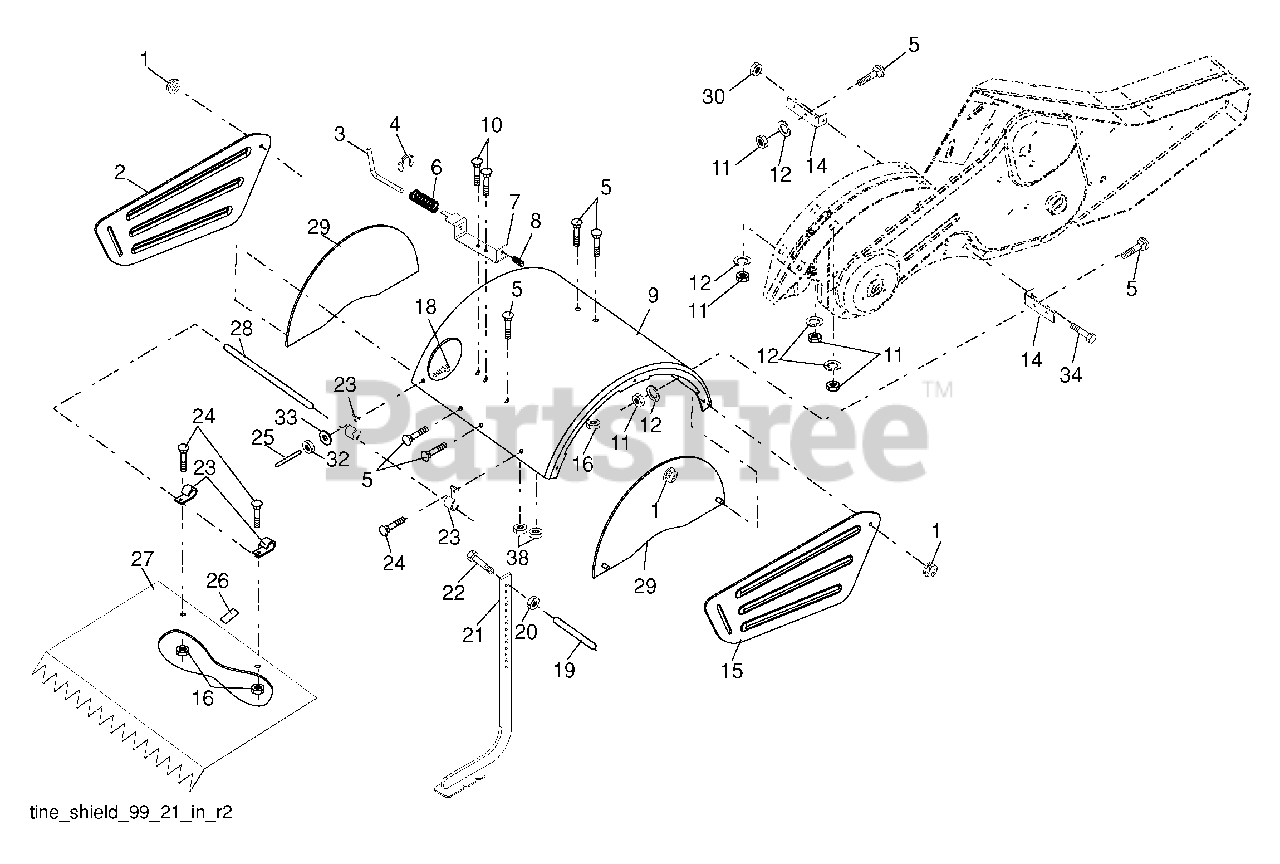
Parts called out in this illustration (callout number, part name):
1	Nut, Lock Hex Flange 5/16-18
2	Shield, Side, Outer L. H.
3	Pin, Stake, Depth
4	Ring, Klip
5	Bolt 5/16-18 x 3/4
7	Bracket, Latch
8	Spring, Depth Stake
9	Shield, Tine
10	Bolt Rdhd Sqnk 5/16-18 x 1
11	Nut, Hex 5/16-18
12	Washer, Lock 5/16
14	Bracket, Shield Tine
15	Shield, Side, Outer R.H.
16	Nut, Flange Hex 1/4-20 unc
18	Bolt, Carriage 1/4-20 x 1-1/4 r. 5
20	Nut, Hex 3/8-16
21	Stake, Depth
22	Bolt, Hex 3/8-16 x 2
24	Bolt, Carriage 1/4-20 x 1/2 Gr. 5
25	Cap, Vinyl
26	Pad, Idler
27	Shield, Leveling
28	Pin, Hinge
29	Shield, Side
30	Nut, Lock Hx Flange
32	Nut, Fin, Hex 1/4-20 unc
33	Washer, Lock Hvy Helical 1/4
34	Bolt Hex Flghd 5/16-18 x 2-1/4
38	Nut Keps 5/16-18 unc
